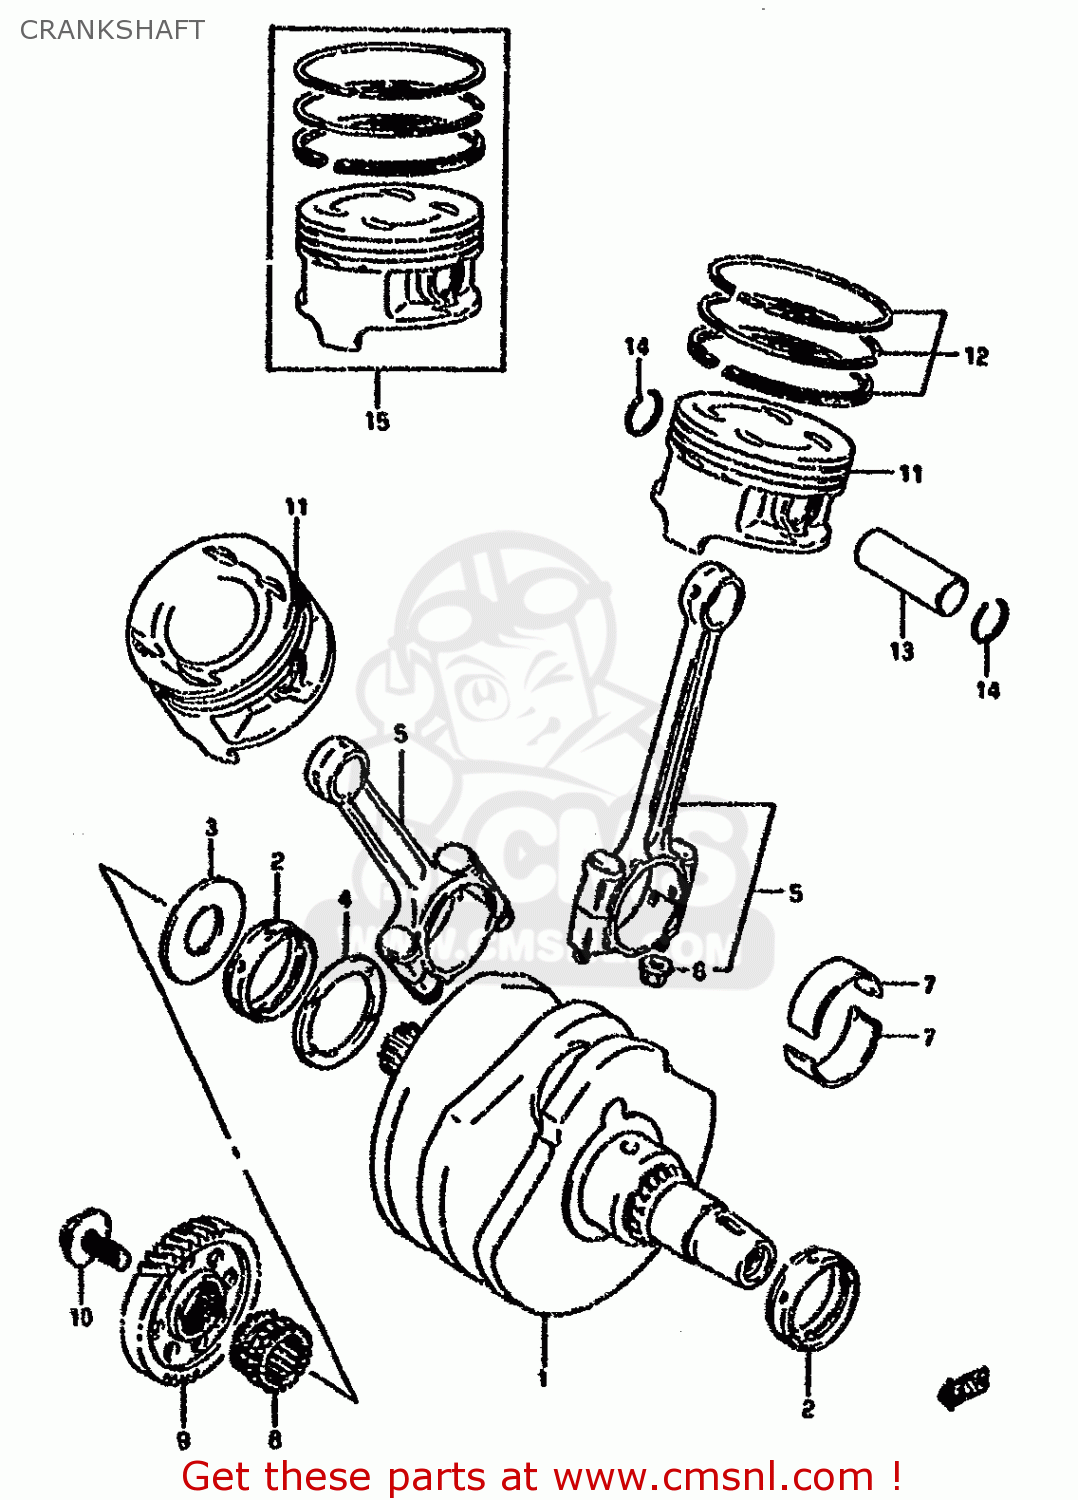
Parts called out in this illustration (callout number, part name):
1	CRANKSHAFT
2	METAL,CRANKSHAFT
3	WASHER,CRANK THRUST
4	WASHER(48.1X64X1.94)
5	CONNROD ASSY
6	NUT
7	BEARING,CRANK PIN
8	SPROCKET,CAM CHAIN DRIVE,R
9	GEAR,PRIMARY DRIVE
10	BOLT(12X28)
11	PISTON
12	RING SET,PISTON
13	PIN,PISTON
14	CIRCLIP,PISTON PIN
15	PISTON SET(OS:0.5)
